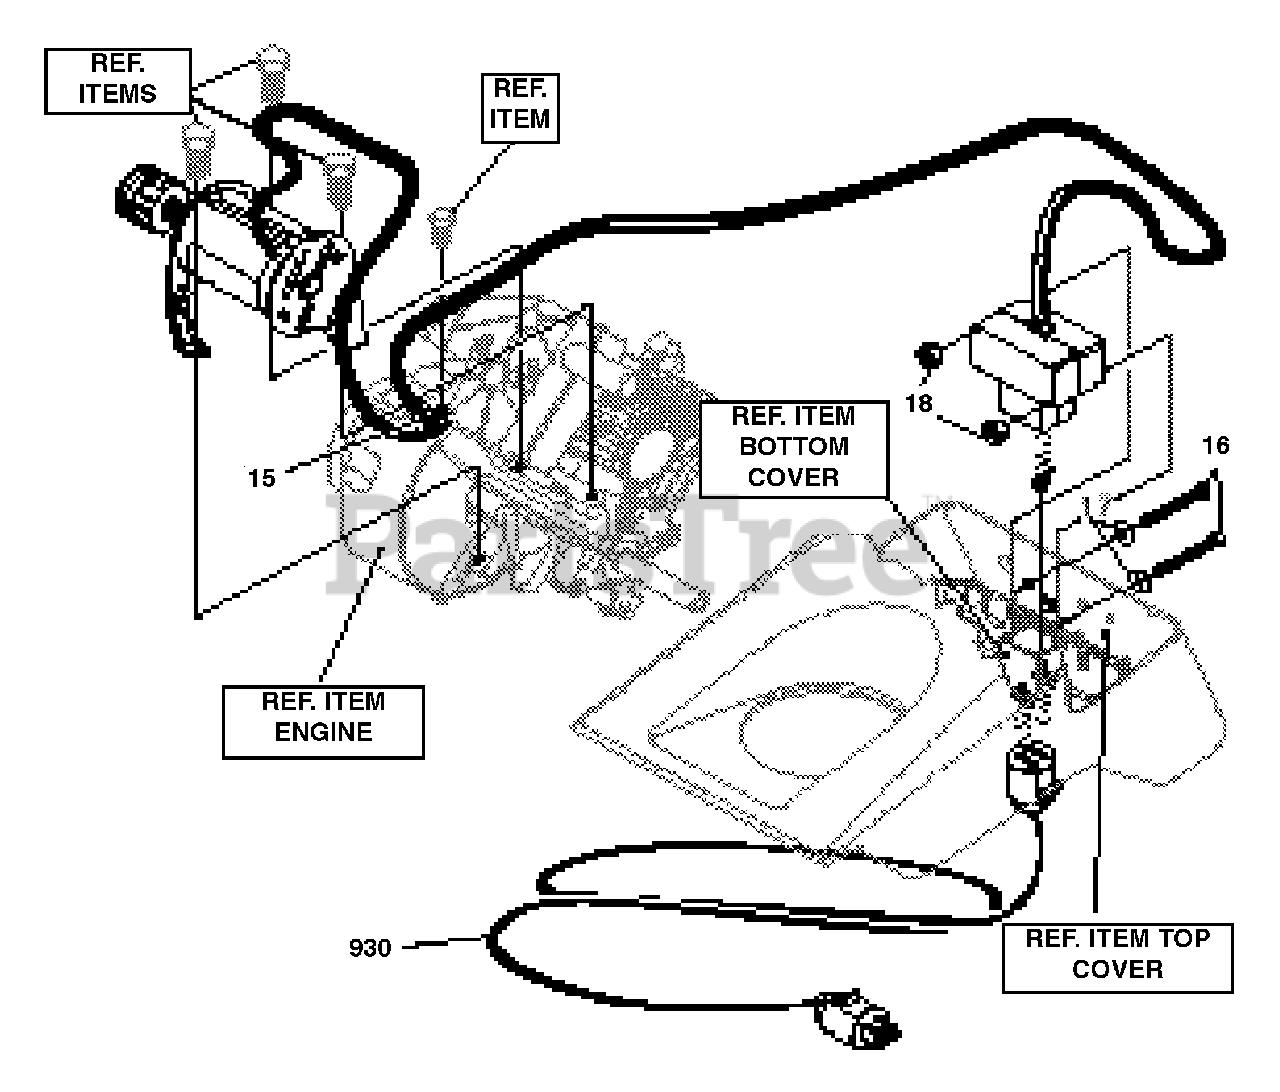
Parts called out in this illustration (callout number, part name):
15	RETAINER, WIRE
16	SCREW, #8-32 X 3.00
17	WASHER, FLAT .188 X .38 X .040
18	NUT, #8-32 HEXKEPS
930	EXTENSION CORD 10FT.
